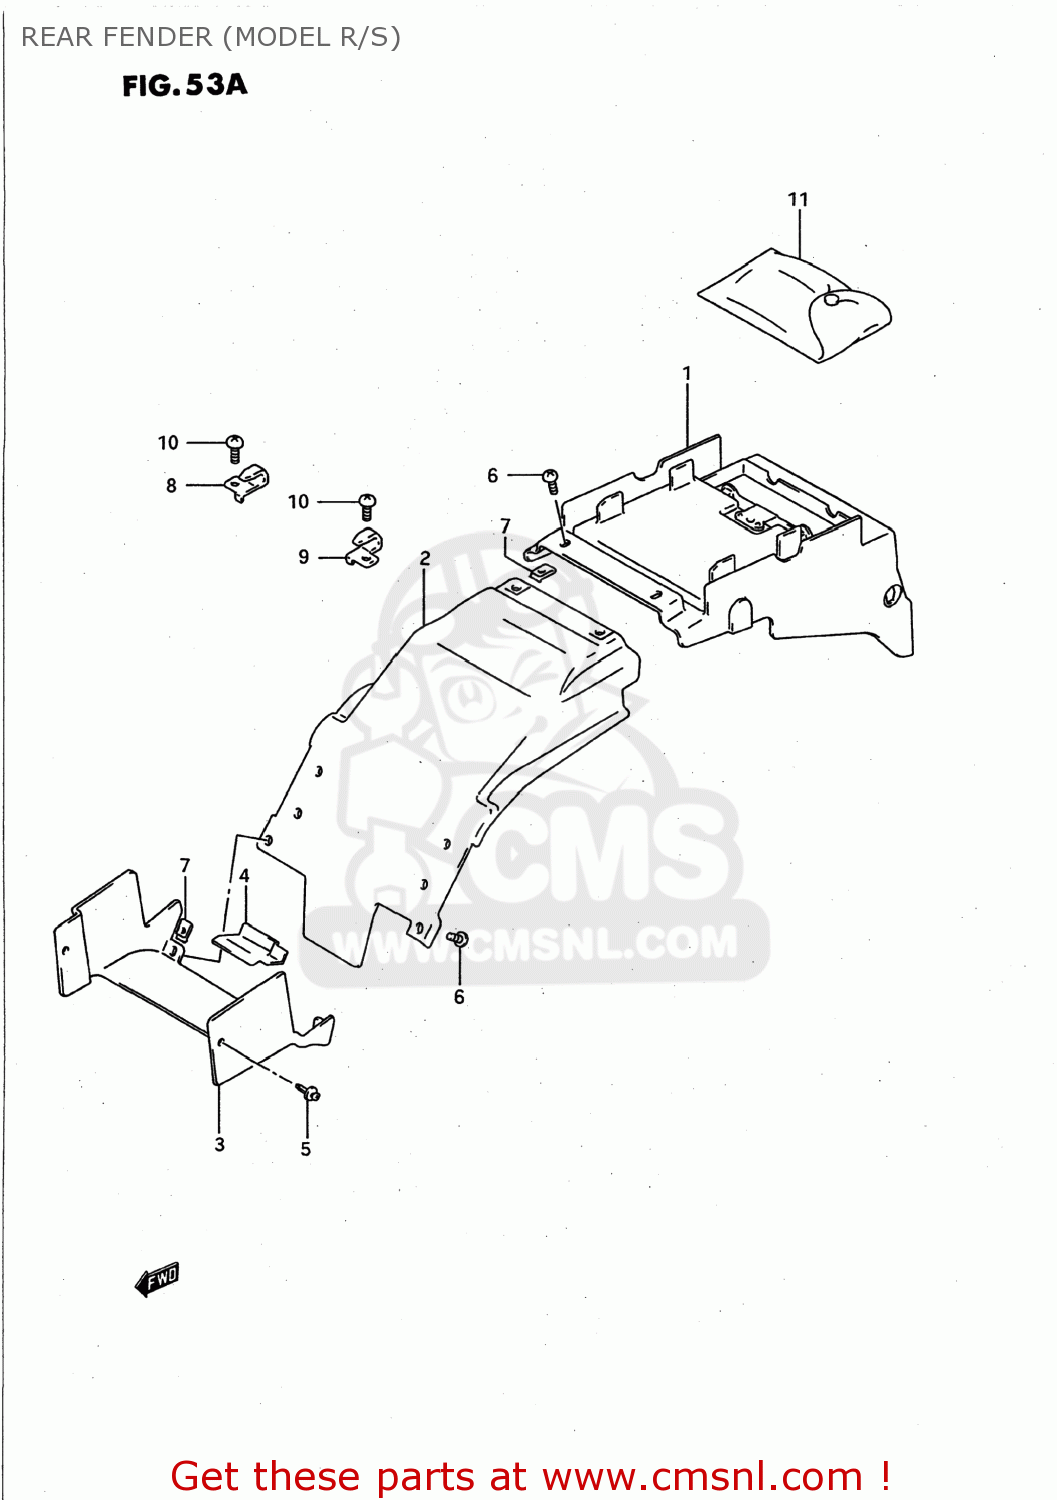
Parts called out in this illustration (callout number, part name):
1	FENDER COMP,REAR,UPPER
2	FENDER,REAR,UPPER,FRONT
3	FENDER,RR UPR FR NO.1
4	MUD GUARD,REAR FENDER
5	CLIP
6	SCREW 5X12
7	NUT,HEADLAMP HOUSING,UPPER
8	HOLDER,HELMET,R
9	HOLDER,HELMET,LEFT
10	SCREW 6X12
11	TOOL ASSY
